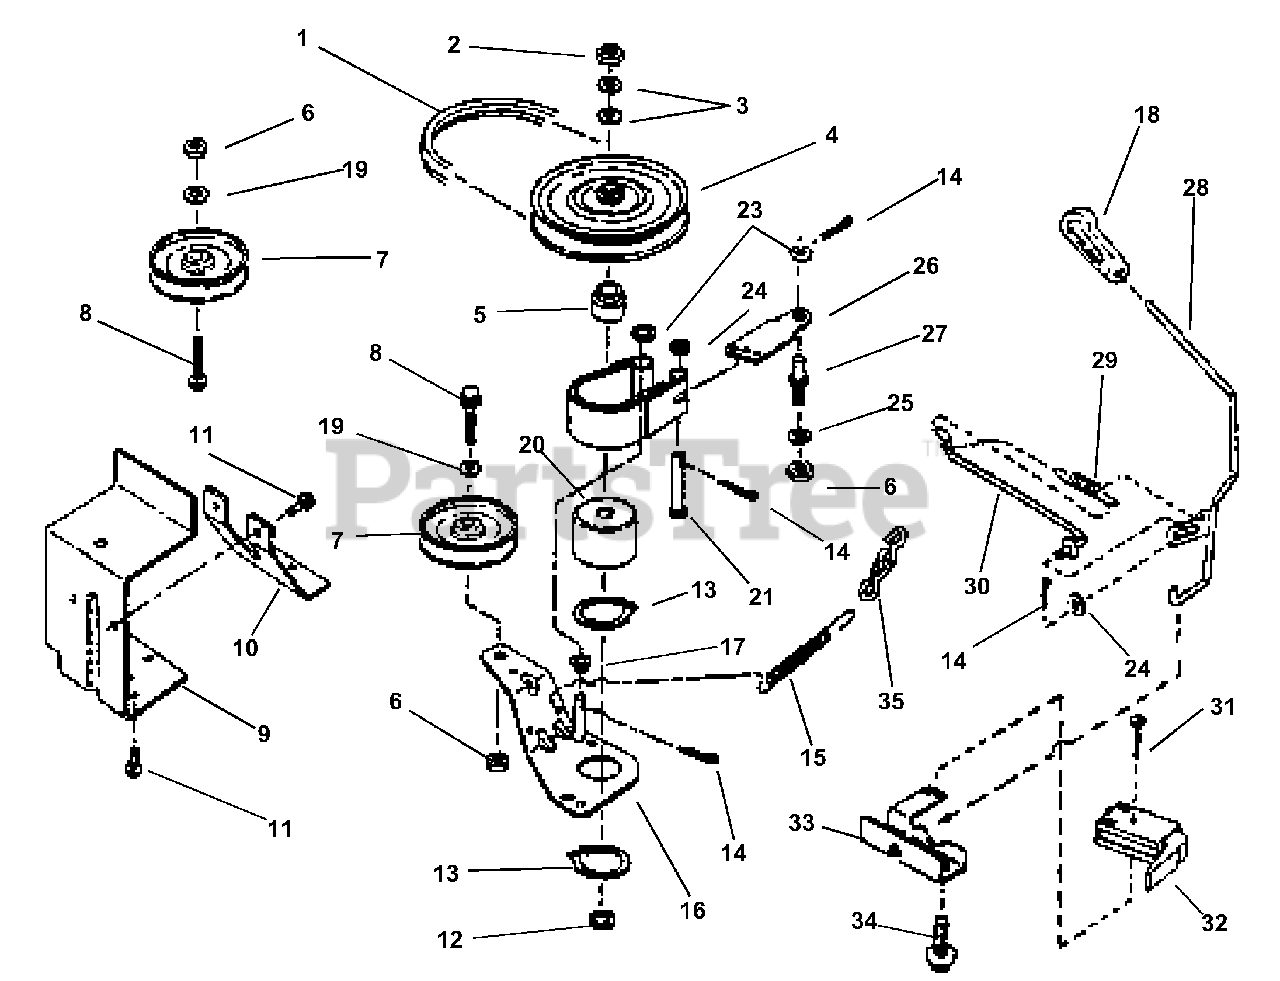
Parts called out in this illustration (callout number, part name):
1	BELT, Drive (73.75" AA Section)
2	NUT, 3/4-16 Hex Jam
3	WASHER, 49/64 x 1-1/2" Flat
4	PULLEY, Spindle
5	HUB, Pulley
6	NUT, 3/8-24 Hex
7	PULLEY, 4" Idler
8	SCREW, 3/8-16 x 1-1/2" Hex Head Cap, Grade 5
9	BRACKET, Fixed Idler
10	BRACE
11	SCREW, 5/16-18 x 1/2" Hex Washer Head, Self-Tapping
12	WASHER, Spindle
13	RING, 2" External Retaining
14	PIN, 3/32 x 3/4" Cotter
15	SPRING
16	ARM, Idler
17	SPACER
18	GRIP, Handle
19	WASHER, 3/8" Flat
20	DRUM, Brake
21	PIN, 1/4 x 1-5/8" Clevis
23	WASHER, 3/8" Flat
24	WASHER, 1/4" Flat
25	WASHER, 3/8" Split Lock
26	BRACKET, Brake Anchor
27	STUD (3/8-24 Thread)
28	HANDLE, Blade Lever (ON-OFF)
29	SPRING, Blade Handle
30	ROD, Idler
31	SCREW, #10-32 x 1" Hex Washer Self-Tap
32	SWITCH, Deck Interlock
33	MOUNT, Handle
34	SCREW, 1/4-20 x 5/8" Hex Washer Self-Tap
35	LINK, Chain
